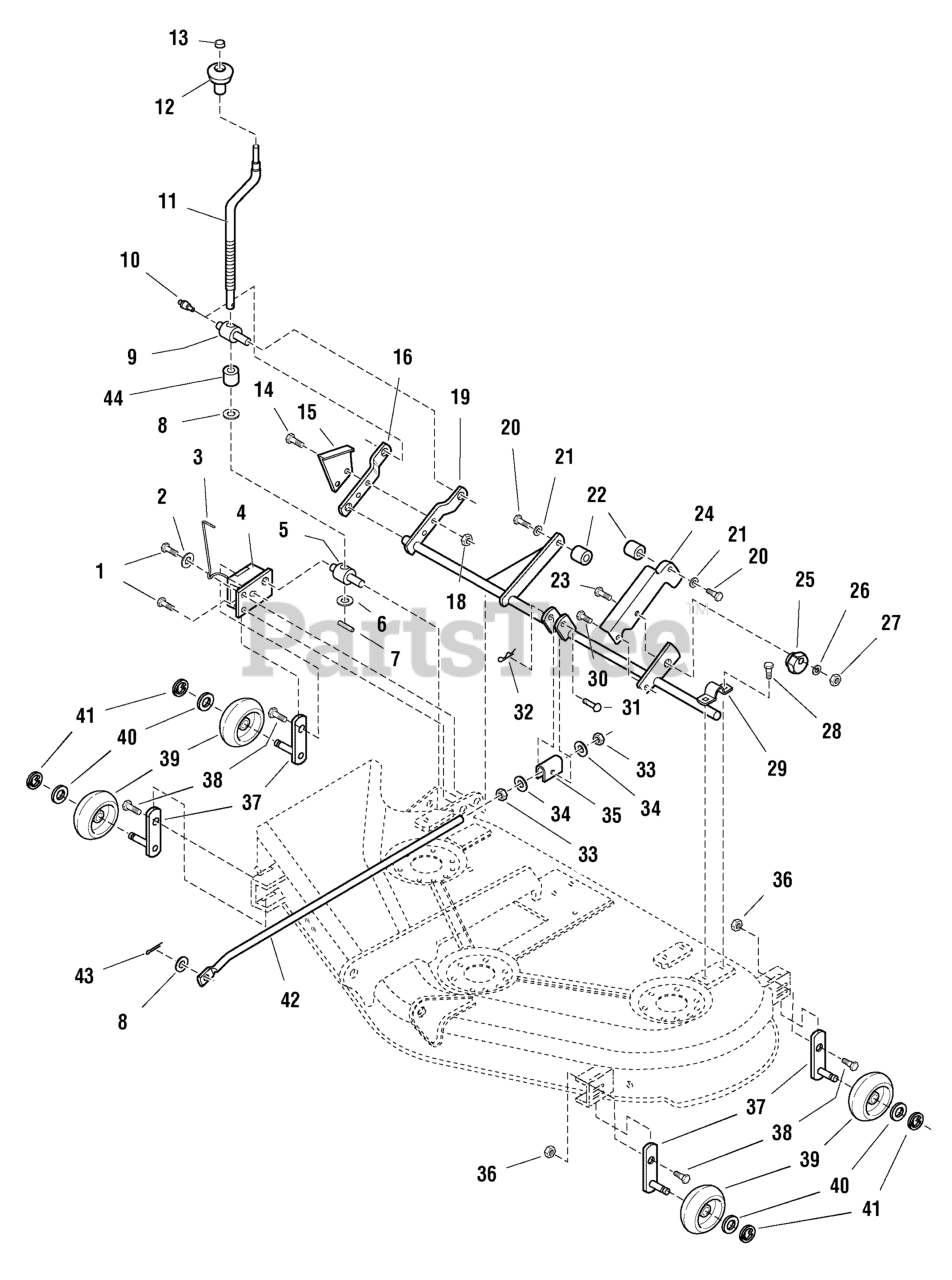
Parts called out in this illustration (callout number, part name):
1	CAPSCREW, Hex Washer Head Taptite, 5/16-18 x 1-1/4
2	WASHER, 5/16
3	ROD, Indicator Height of Cut
4	PLATE & BRACKET ASSEMBLY, Gauge Wheel
5	TRUNNION, 1-1/4
6	WASHER, Detent
7	PIN, Spring
8	WASHER, 9/16
9	TRUNNION, 1-1/4
10	FITTING, Lube
11	CRANK, Height Adjustment
12	KNOB, Spinner, Soft
13	NUT, Push
14	CAPSCREW, Hex Head, 5/16-18 x 1 1/4
15	BRACKET, Height of Cut
16	ARM, Rear
18	NUT, Hex, 5/16-18
19	ARM ASSEMBLY, Roller Bar
20	CAPSCREW, Hex Head, 3/8-16 x 1, G5
21	LOCKWASHER, Spring, 3/8
22	SPACER, Support
23	CARRIAGE BOLT, 5/16-18 x 1-1/4, G5
24	ARM, Rear Adjustable
25	CAM, Eccentric, Hex
26	WASHER, 5/16
27	NUT, Hex Flange Collar Lock , 5/16-18
28	CAPSCREW, Hex Washer Head Taptite, 5/16-18 x 3/4
29	STRAP
30	CAPSCREW, Hex Washer Head Taptite, 5/16-18 x 1
31	PIN, Round Head, Drilled, 3/8 x 2
32	PIN, Hair, 3/32
33	NUT, Hex Jam, 5/8-11
34	WASHER, 5/8
35	TRUNNION
36	NUT, Hex Flange Toplock 1/4-20
37	SHAFT & BAR ASSEMBLY, Roller Fixed Arm
38	CAPSCREW, Hex Head, 1/4-20 x 3/4, G5
39	WHEEL, Roller
40	WASHER, 1/2
41	E-RING, Retaining Extenstion
42	ROD, Pitch
43	PIN, Cotter, 1/8 x 3/8
44	SPACER, .66 X 7/8 X 1 1/4
